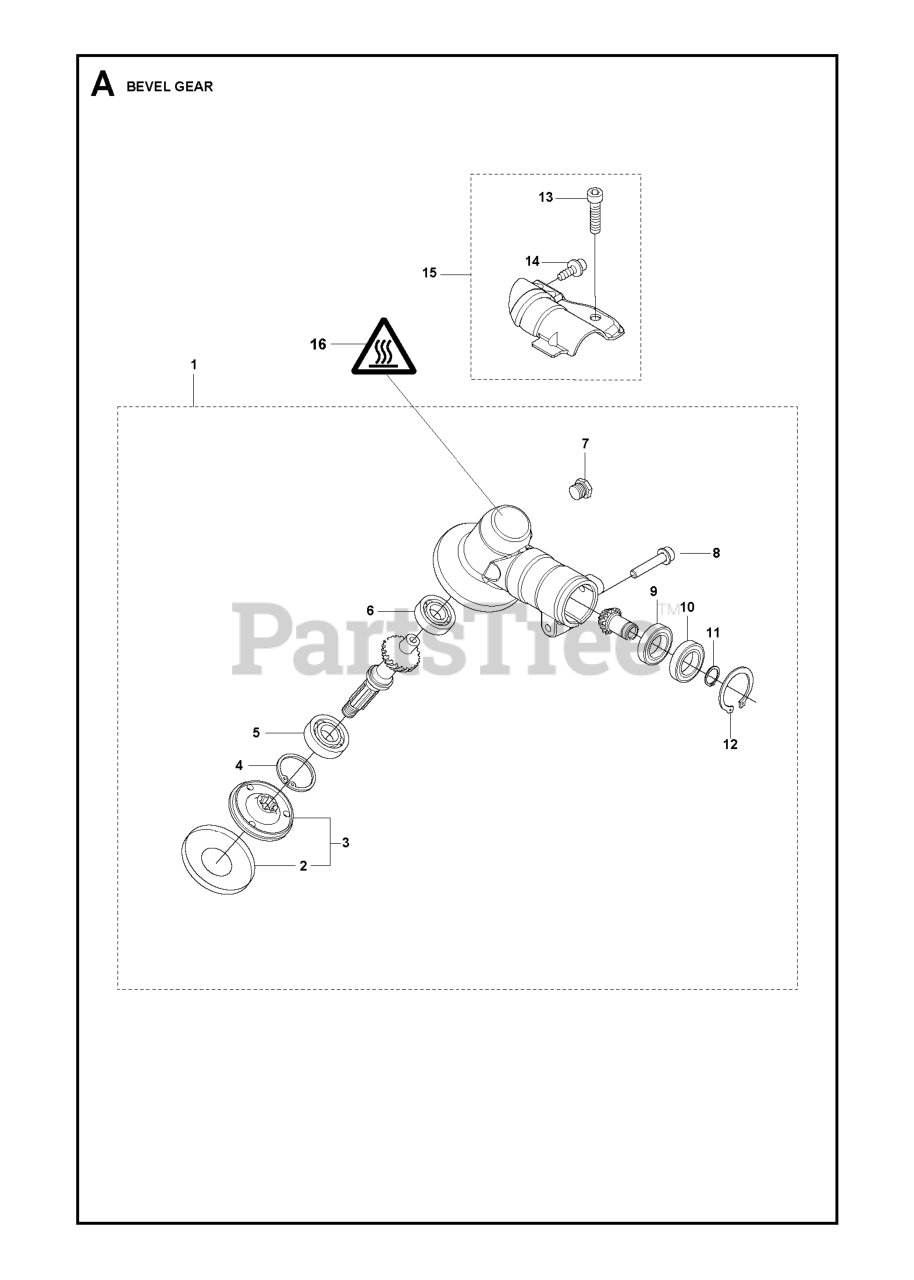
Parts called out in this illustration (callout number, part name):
2	WASHER
3	DRIVE DISC
4	RETAINING RING SGH 28
5	BEARING
6	BALL BEARING 8X22X7/608Z
9	BALL BEARING 24X9X1/609ZR
11	RETAINING RING
12	RETAINING RING
13	SCREW IHSCM M6X22 10.9 ZN/FE
